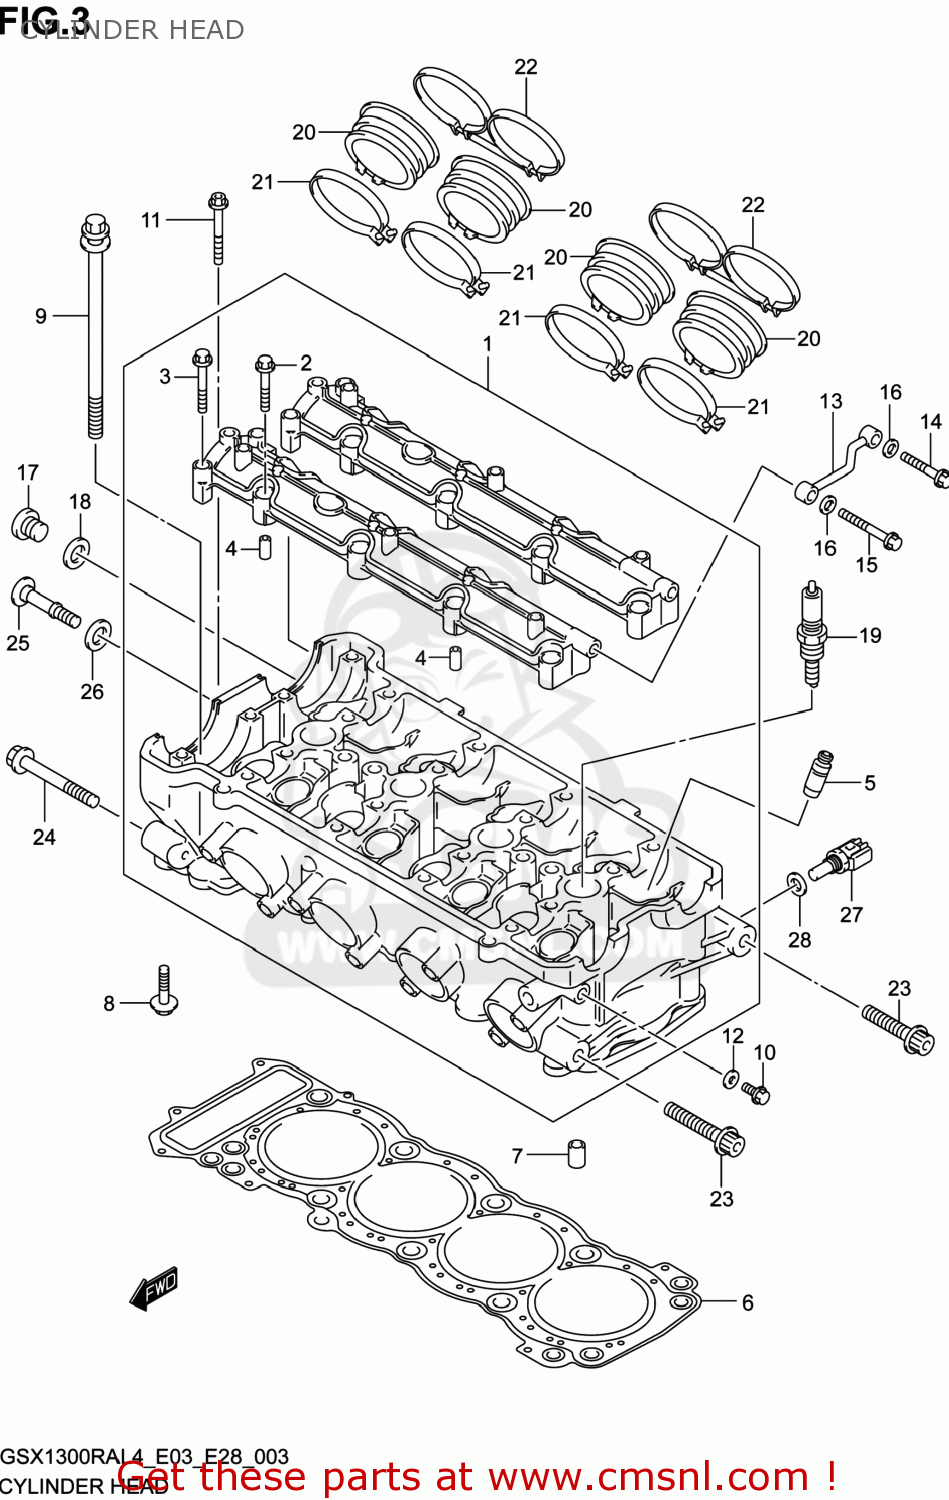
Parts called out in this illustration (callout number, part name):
1	HEAD ASSY,CYLINDER
2	BOLT(6X40)
3	BOLT(6X45)
4	PIN(6.2X8X16)
5	GUIDE,VALVE(OS:0.3)
6	GASKET,CYLINDER HEAD (NAS)
7	PIN
8	BOLT
9	BOLT,CYLINDER HEAD(L:180)
10	BOLT(6X12)
11	BOLT
12	GASKET(5.8X13X1.2) (NAS)
13	PIPE,CYL HEAD OIL
14	BOLT
15	BOLT
16	WASHER
17	PLUG,16X8
18	GASKET(16X22X0.8) (NAS)
19	PLUG,SPARK(IU27D)
20	PIPE,INTAKE
21	CLAMP
22	CLAMP,INTAKE PIPE
23	BOLT(10X45)
24	BOLT(10X60)
25	BOLT,CYL HEAD SIDE FACE
26	WASHER,HEAD COVER
27	SENSOR,TEMP
28	GASKET(12X17X1) (NAS)
